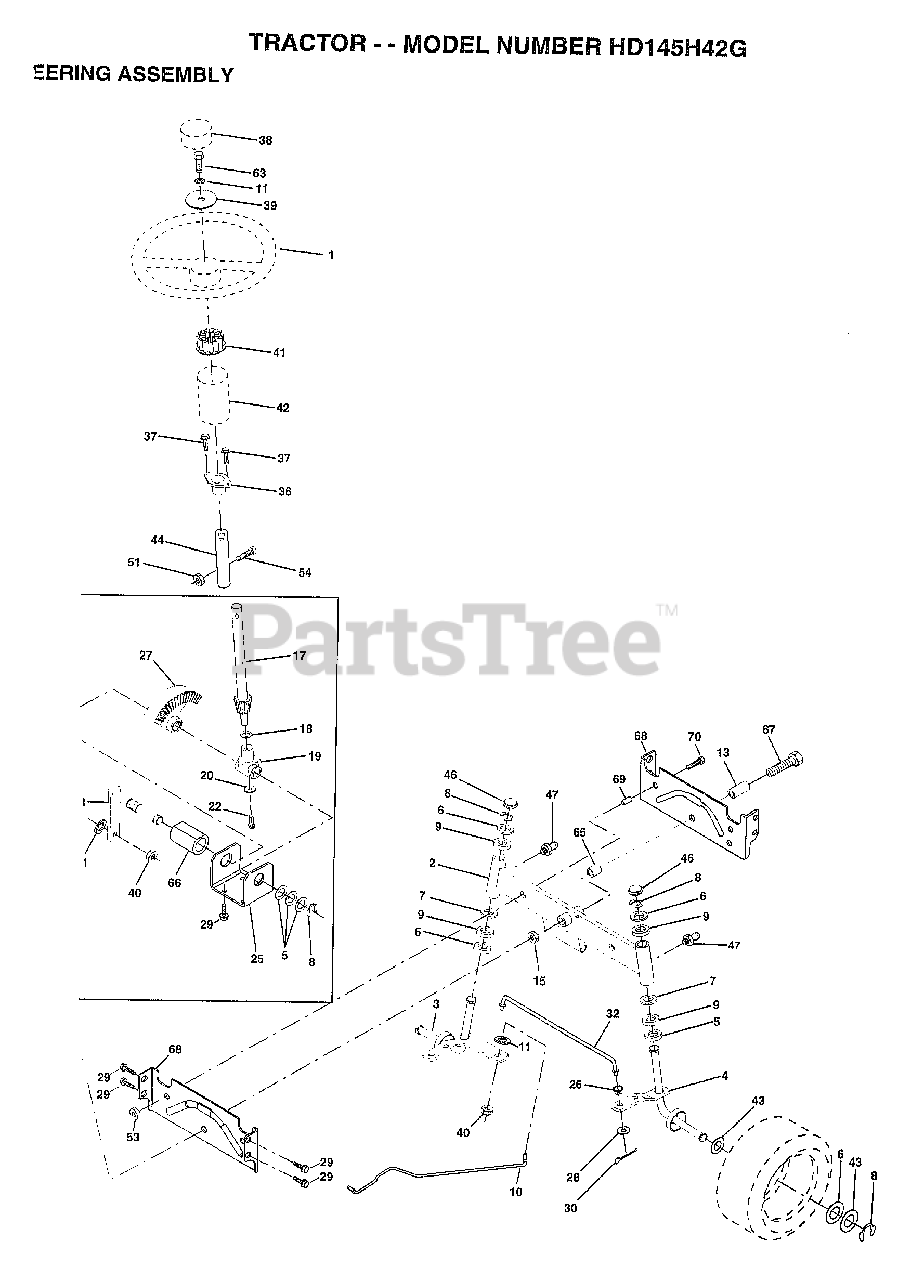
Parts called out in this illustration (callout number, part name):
1	WHEEL STR AYP BLK
2	AXLE ASM
3	SPINDLE.ASM.LH
4	"SPINDLE ASM,RH"
5	WASHER .T
6	WASHER
7	WASHER
8	RING
9	COL. SRTG. BEAR.
10	DRAGLINK-STAMPED
11	LOCKWASHER
13	BEARING AXLE
15	"NUT-LOC,FLANGE LT"
17	SHAFT ASM STEERIN
18	THRUST WASHER
19	SUPPORT.SHAFT
22	SCREW HEX SOC1/4-
25	BRKT-STEERING
26	BUSHING.DRAGLINK
27	GEAR SECTOR
28	WASHER
29	SCREW
30	COTTER PIN
32	TIE ROD
36	BUSHING.STEERING
37	"SCREW-TT,10-32 FL"
38	CAP STEER AYP
39	WASHER T
40	GRIPCO NUT
41	ADAPTER LT
42	BOOT.STEER.PL
43	WASHER
44	EXT SHAFT STEERIN
46	CAP
47	ZERK M
51	NUT
54	BOLT
62	KIT STEERING ASM
63	BOLT
65	SPACER AXLE
66	"BEARING-ARM,PITMA"
67	BOLT
68	BRACE AXLE
69	"SPACER BRCAE,AXLE"
70	BOLT.HEX.3/8-16X2
